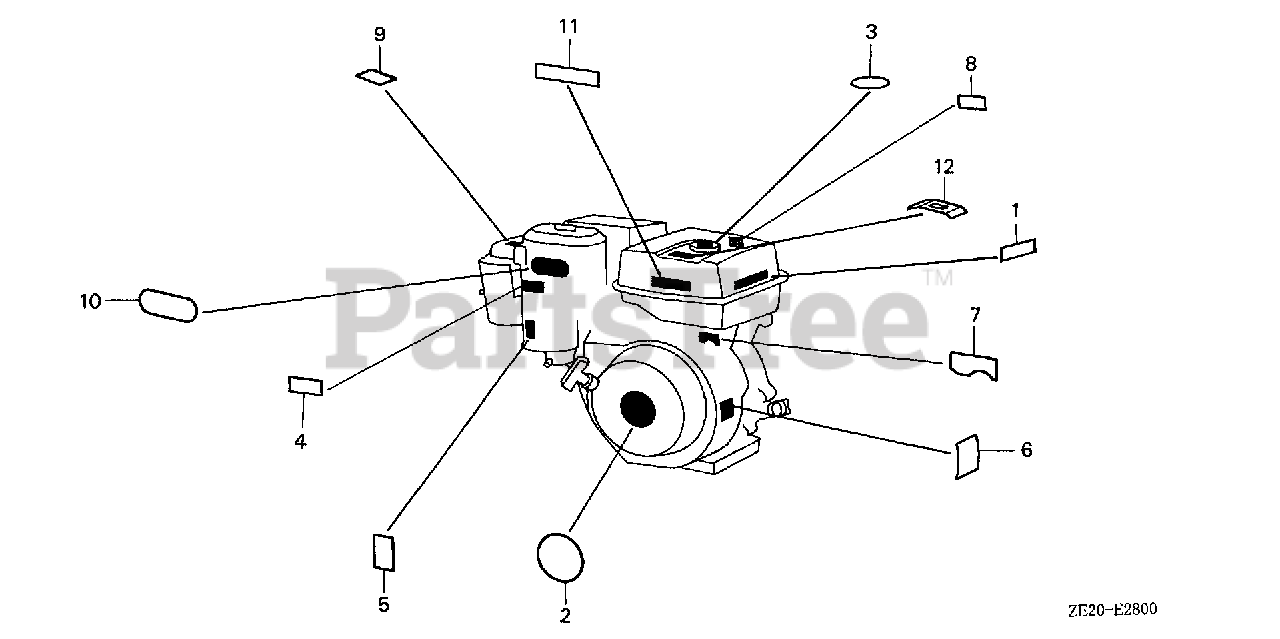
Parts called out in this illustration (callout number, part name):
5	MARK, CHOKE (ORANGE)
6	SUB EMBLEM (EXTERNAL)
7	MARK, OIL ALERT (EXTERNAL)
9	LABEL, AIR CLEANER CAUTION
10	MARK, AIR CLEANER SALES POINT
